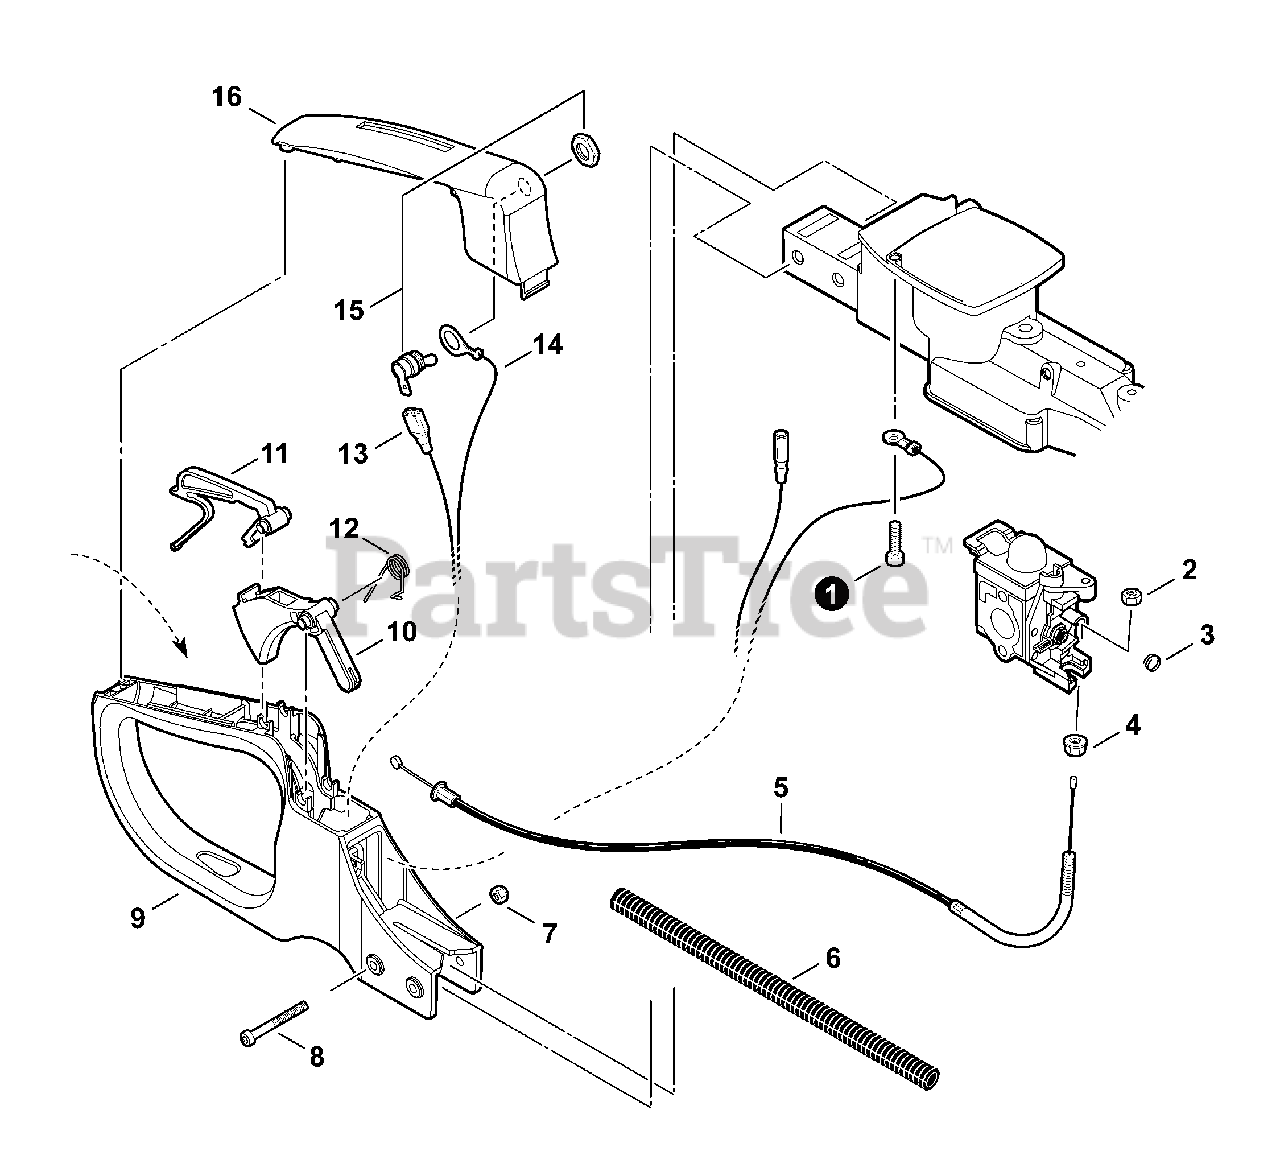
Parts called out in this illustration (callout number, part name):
1	BOLT, TORX 4×16
4	NUT, FLANGE 6
5	CABLE, THROTTLE
6	TUBE, FLEXIBLE
7	NUT, FLANGE M5
8	BOLT, TORX 5
9	HANDLE, REAR
10	TRIGGER, THROTTLE
11	LOCKOUT, THROTTLE
12	SPRING, TORSION
13	LEAD - IGNITION L= 260
14	LEAD - GROUND L= 280
15	SWITCH, ON-OFF
16	COVER, HANDLE
